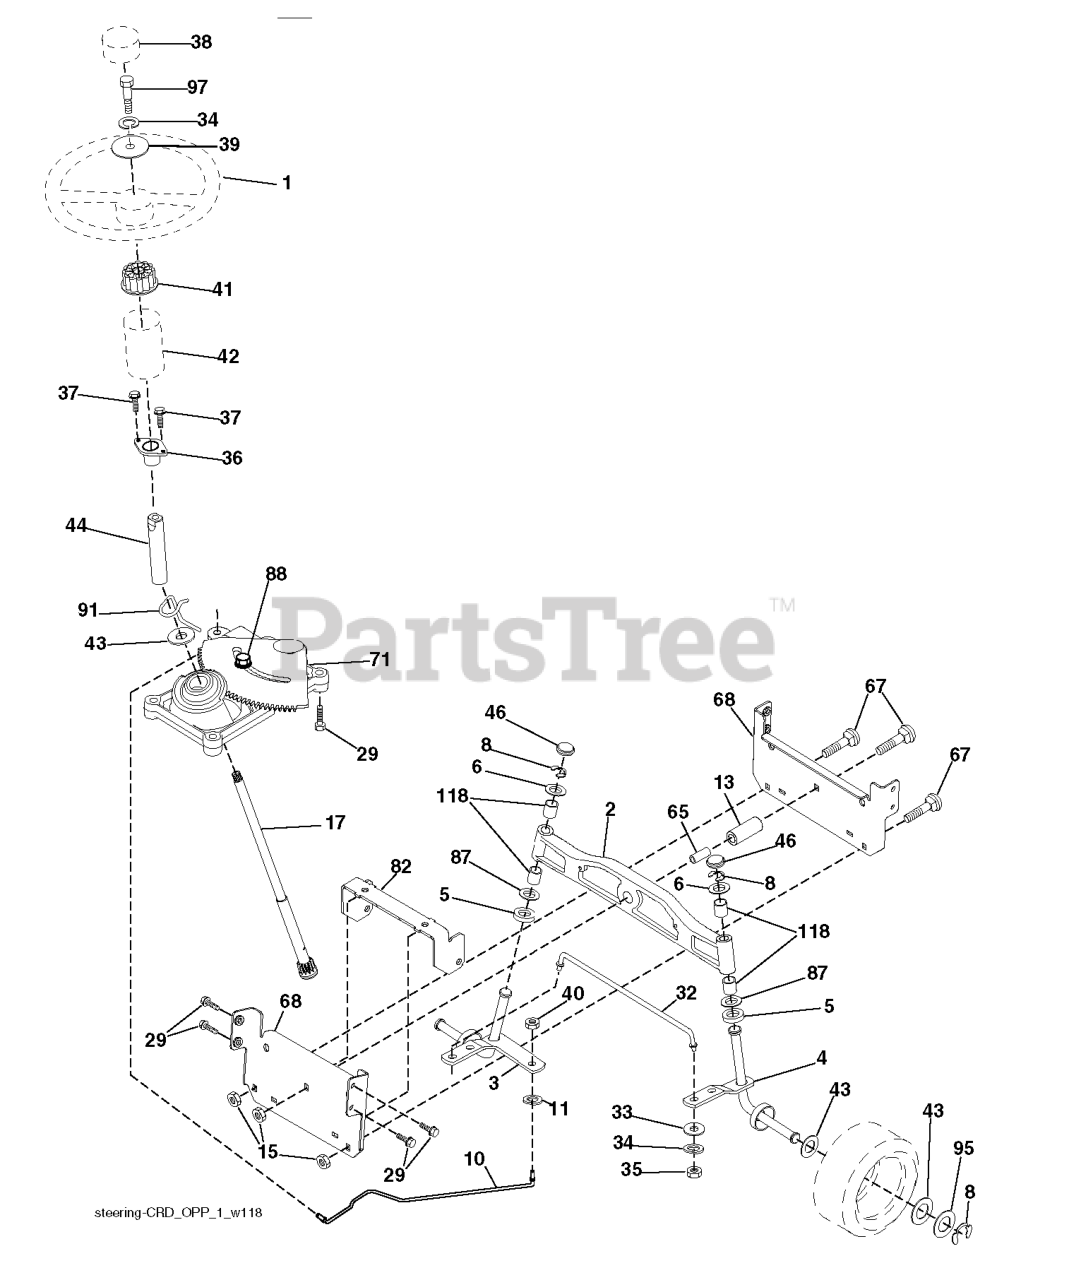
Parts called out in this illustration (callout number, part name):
1	WHEEL.STEERING.OPP.BLACK
2	AXLE.ASM.LT.CAST.LGHTWGHT
3	SPINDLE.ASM.LH.15"TIRES
4	SPINDLE.ASM.RH.15"TIRES
5	THRUST WASHER
10	DRAGLINK.15".TIRES.2001
11	WASHER, LOCK 3/8
13	TUBE, PIVOT AXLE
15	NUT LOCK FLG 3/8-16 UNC
17	SHAFT STEERING SPLINE
29	SCREW, 3/8-16X3/4
32	ROD.ASM.TIE.BALL.JOINT.NOVAN
33	WASHER M
34	WASHER.LOCK.HVY.HLCL.SPR.5/16
35	NUT, CROWNLOCK
36	BUSHING, STEERING
37	SCREW.TT.#10-32X.5.3/8.FLANGE
38	CAP.WHEEL.STEER.OPP.BLK
39	WASHER.11/32
40	NUT CROWNLOCK 3/8-24
41	ADAPTER, WHEEL STNG..
42	BOOT.STEERING.SHAFT.BLACK
44	SHAFT.EXTEN.STRG.SPLINE
46	CAP.SPINDLE.BLACK
65	SPACER.BRACE.AXLE
67	BOLT CARRIAGE
68	BRACE.AXLE.15"TIRES
71	STEERING ASM
82	BRACKET.SUSP.CHASSIS.FRONT.15
87	WASHER, FLAT .781 X 1 1/2"
88	BOLT, SHOULDER 7/16-20
91	CLIP.STEERING
95	WASHER.HARDENED
97	BOLT 5/16-18 X 4 W/PATCH
118	BUSHING, AXLE CAST
